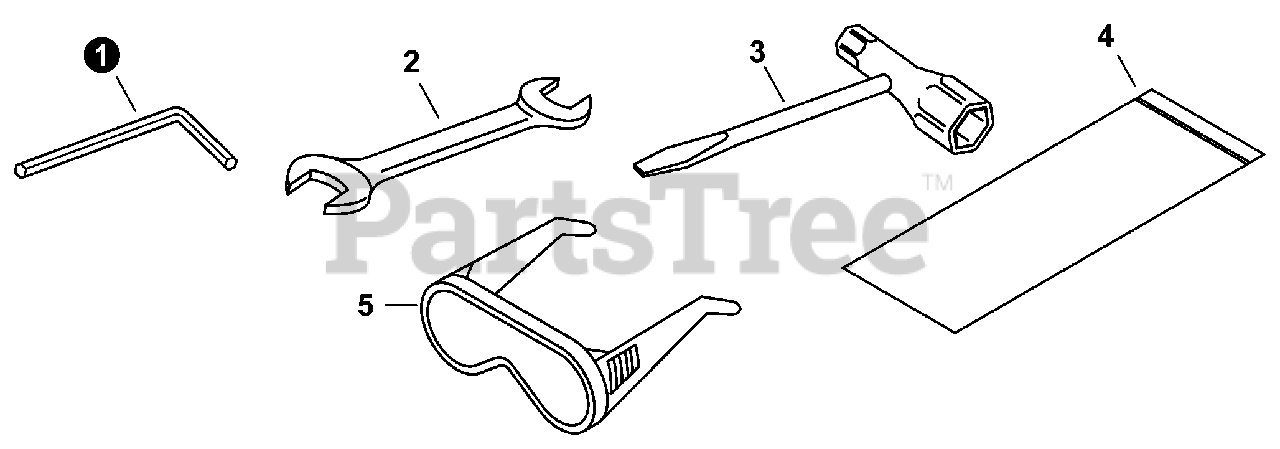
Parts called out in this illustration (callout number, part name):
1	WRENCH, ALLEN 4 MM
2	SPANNER 8x10
3	T-WRENCH 13x19 MM
4	BAG, TOOL
5	GLASSES, SAFETY
